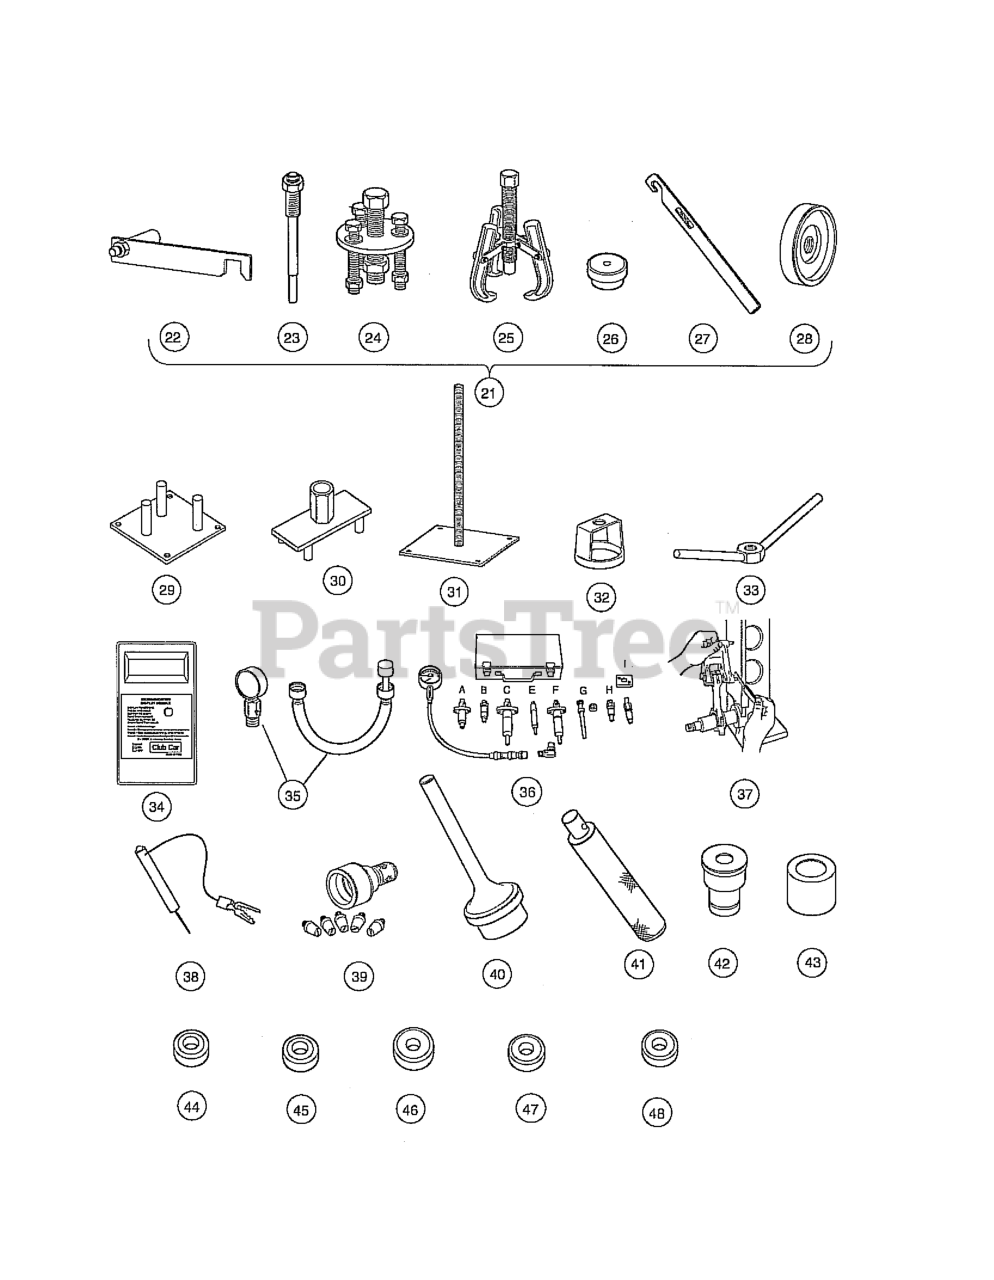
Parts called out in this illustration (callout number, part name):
21	C.C. CLUTCH TOOL KIT
22	TOOL, CLUTCH ALIGNMENT
23	TOOL, CLUTCH PULLER
24	CLUTCH DRIVE HUB PULLER
25	DRIVEN CLUTCH CAM PULLER
26	DRIVEN CLUTCH PULLER PLUG
27	DRIVE CLUTCH HOLDER TOOL ASM.
28	PRESS WELDMENT
29	TOOL-STATIONARY PRIMARY
30	TOOL-SPIDER PRIMARY
31	TOOL-SPRING COMPRESSION BASE
32	TOOL-SPRING COMPRESSION COLAR
33	TOOL-SPRING COMPRESSION COLAR
34	COMMUNICATION DISPLAY MODULE
35	COMPRESSION GUAGE AND ADAPTER
